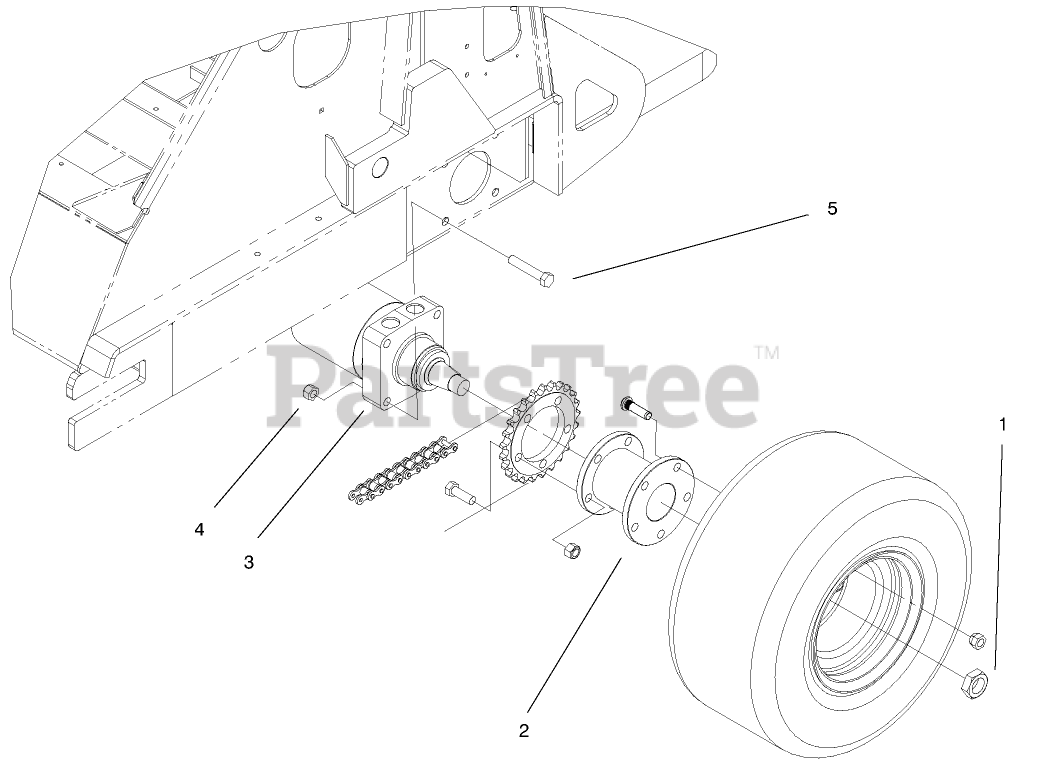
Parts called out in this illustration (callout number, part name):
1	NUT-LOCK
2	HUB - REAR
3	HYDRAULIC MOTOR ASM
4	NUT-LOCK, HEX NI
